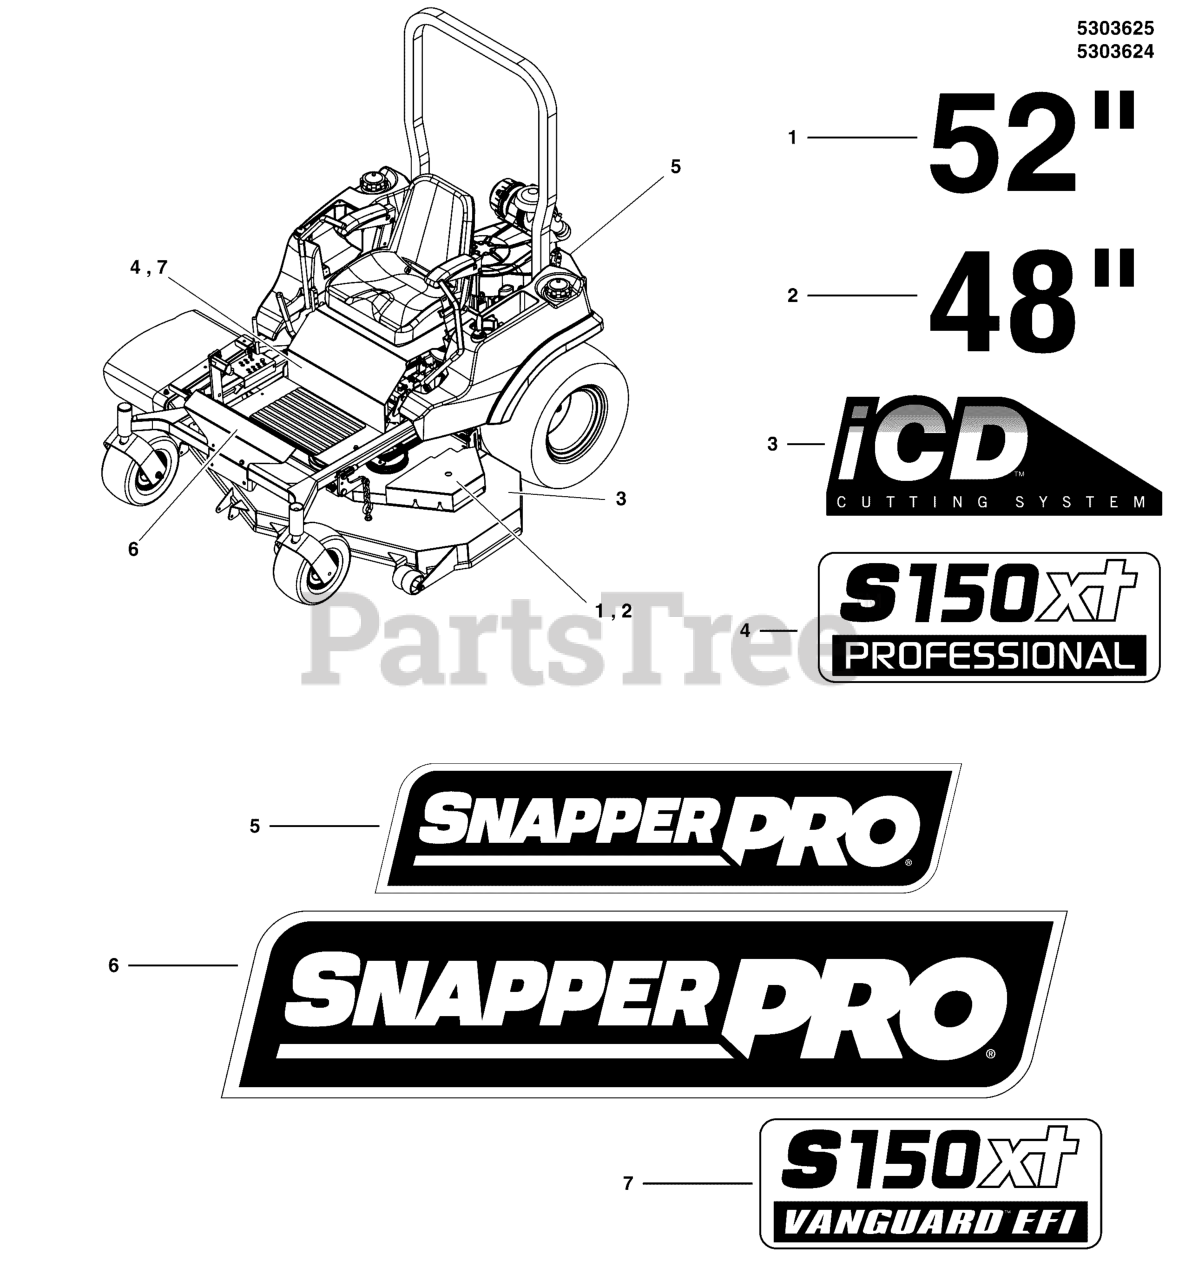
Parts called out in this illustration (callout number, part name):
1	DECAL, 52
2	DECAL, 48
3	DECAL, iCD CUTTING SYSTEM
4	DECAL, S150XT (2014)
5	DECAL, SNAPPER PRO LOGO, SMALL
6	DECAL, SNAPPER PRO LOGO, MEDIUM
7	DECAL, MODEL SERIES, S150XT, EFI
